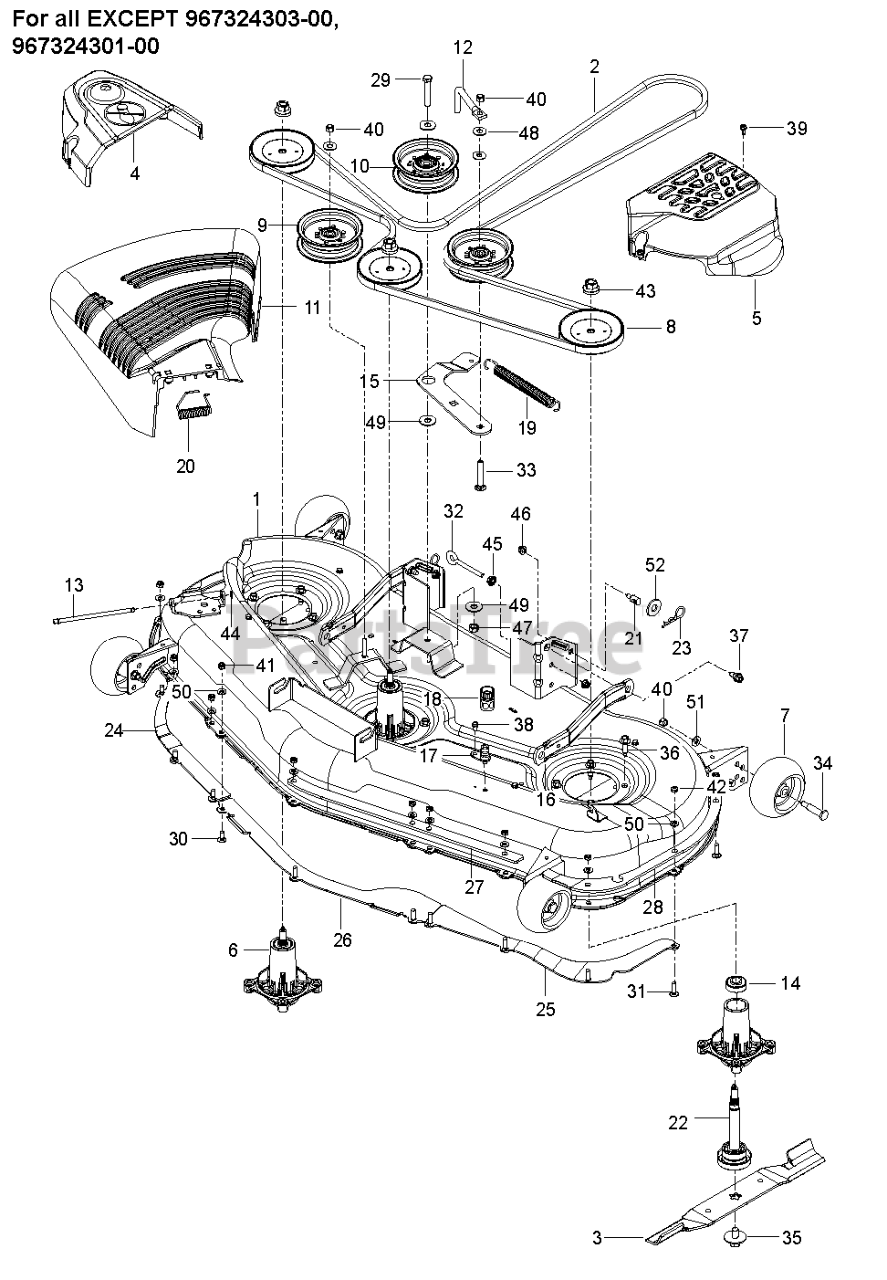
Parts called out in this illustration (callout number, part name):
1	DECK SVC W/DECALS 54" ORG
2	BELT.DECK.52".54"
3	BLADE.BAGGING.54"
4	COVER.MANDREL.RH.DECK.54"
5	COVER.MANDREL.LH.DECK.54"
6	MANDREL.W/SPCR.BRG.TALL.NONREV
7	WHEEL.GAUGE.RALLY
8	PULLEY MANDREL
9	PULLEY.IDLER.2006
10	PULLEY.IDLER.MWR.STATI.LH
11	DEFLECTOR.BLACK.54"
12	BELT KEEPER 5"
13	ROD.HINGE
15	ARM IDLER RAW
15	ARM ARM.IDLER.54". RZ BLACK MS
16	ARM.SUSPENSION.MOWER
17	PORT.WASHOUT
18	COUPLING.QUICK CONNECT
19	SPRING, DECK BELT
20	SPRING, TORSION
21	STUD.FASTNER.W/ANTI-ROTATE
22	SHAFT ASM MANDREL
23	HAIRPIN #4
24	BAFFLE.RIGHT.54"
25	BAFFLE.LEFT.54"
26	BAFFLE CENTER 54" MOWER
27	PLATE.REIN.FRONT.BOLT54"X431
28	PLATE.REIN.SIDE.BOLT.54"X431
29	BOLT.HEX.7/16-14
31	BOLT.CARRIAGE.5/16-18
32	EYE BOLT 5/16 X 3.50
33	CARRIAGE BOLT 3/8-16 X
34	BOLT.SHOULDER.3/8-16X3-5/8.
35	SCREW.SEMS.7/16-20X1.HEX.HEAD
36	BOLT.HEX.WASHR.HED.313-18X1.19
37	BOLT.SHOULDER
38	SCREW
39	SCREW.1/4-20X5/8
40	NUT 3/8-16 NYLOC
40	NUT
41	NUT.71038.31-18.HEX.NYLOCK
42	LOCKNUT
42	NUT.71038.31-18.HEX.NYLOCK
43	NUT.FLANGE.LOCK.TOP
44	NUT PUSH M
45	NUT 5/16C WHIZ
46	5/16-18 NYLOC FLANGE NUT
47	7/16-14 HEX NUT W/NYL RING ZD
48	RP WASHER 3/8 FLAT
49	WASHER 7/16 FLAT ZD
50	WASHER
51	WASHER
52	WASHER
